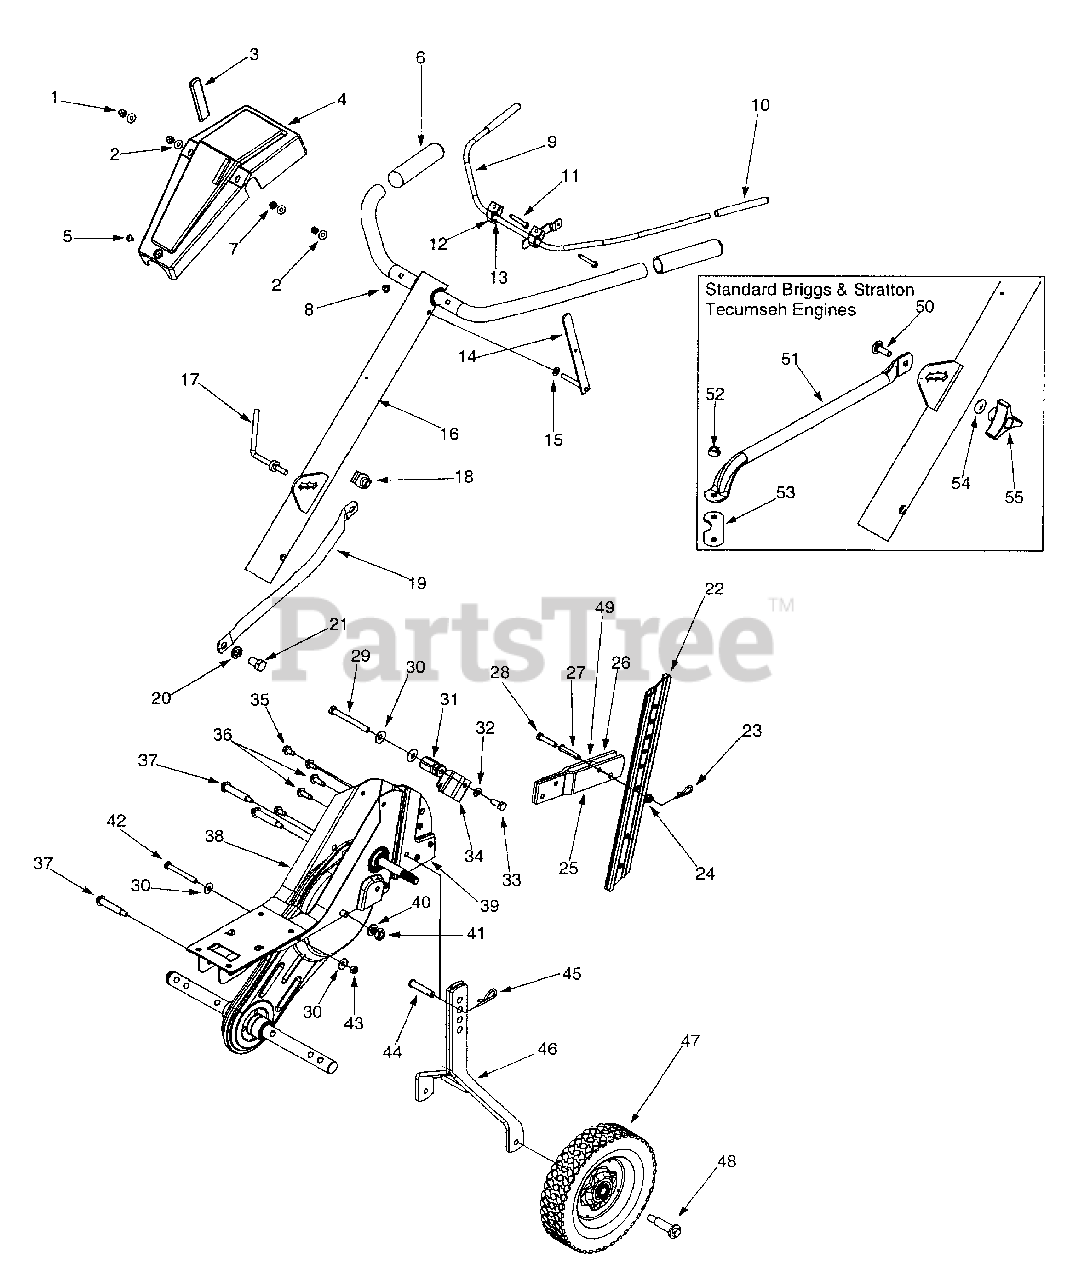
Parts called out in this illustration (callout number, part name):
1	Acorn Lock Nut 1 /4-20
2	Flat Washer.271" I.D. x .630" O.D.
3	Reverse Handle Grip
4	Handle Cover w/o throttle
5	Truss Mach. Scr. #10 x 1/2" Lg.
6	Grip-Handle
7	Hex Nut 1/4-20 Gr.2
8	Cap Speed Nut
10	Grip-Clutch
11	Hex Bolt 1/4-20 x 2.25" Lg. Gr.5
12	Clutch Handle Holder
13	Flat Washer.385" I.D. x .62" O.D.
15	Flat Washer.344" I.D. x .62" O.D.
18	U Nut 5/16-18
21	Hex Bolt 1/2-20 Gr. 5
23	Cotter Pin
24	Hex Flange L-Nut 5/16-18 Thd. Gr.5
27	Clevis Pin
28	Hex Bolt 5/16-18 x 1.5" Lg.
29	Hex Bolt 5/16-18 x 3" Lg.
30	Wash. Bell. .340" I.D. x .872" O.D.
31	Spec. Hex Nut
32	L-Wash. 5/16" I.D.
33	Hex Bolt 5/16-18 Gr. 5
35	Hex Wash. Hd. TT Tap Scr. 5/16-18 x .62" Lg.
36	Hex Wash. Hd. TT Tap Scr.
37	Shdl. Bolt 5/16-18
40	Lock Washer 7/16
41	Jam Nut 7/16-20 Gr. 2
42	Hex Bolt 5/16-18 x 2.75" Lg.
43	Hex Nyloc Nut 5/16-18 Thd.
44	Clevis Pin
45	Cotter Pin
47	Wheel Ass'y 8" x 1.75"
48	Shoulder Screw.496 I.D. x 1.445 O.D.
49	Spacer
50	Carr. Bolt 5/16-18 x 1
53	Engine Brkt. (Std. B&S)
54	Bell. Wash. .34" I.D.
55	Hand Knob
